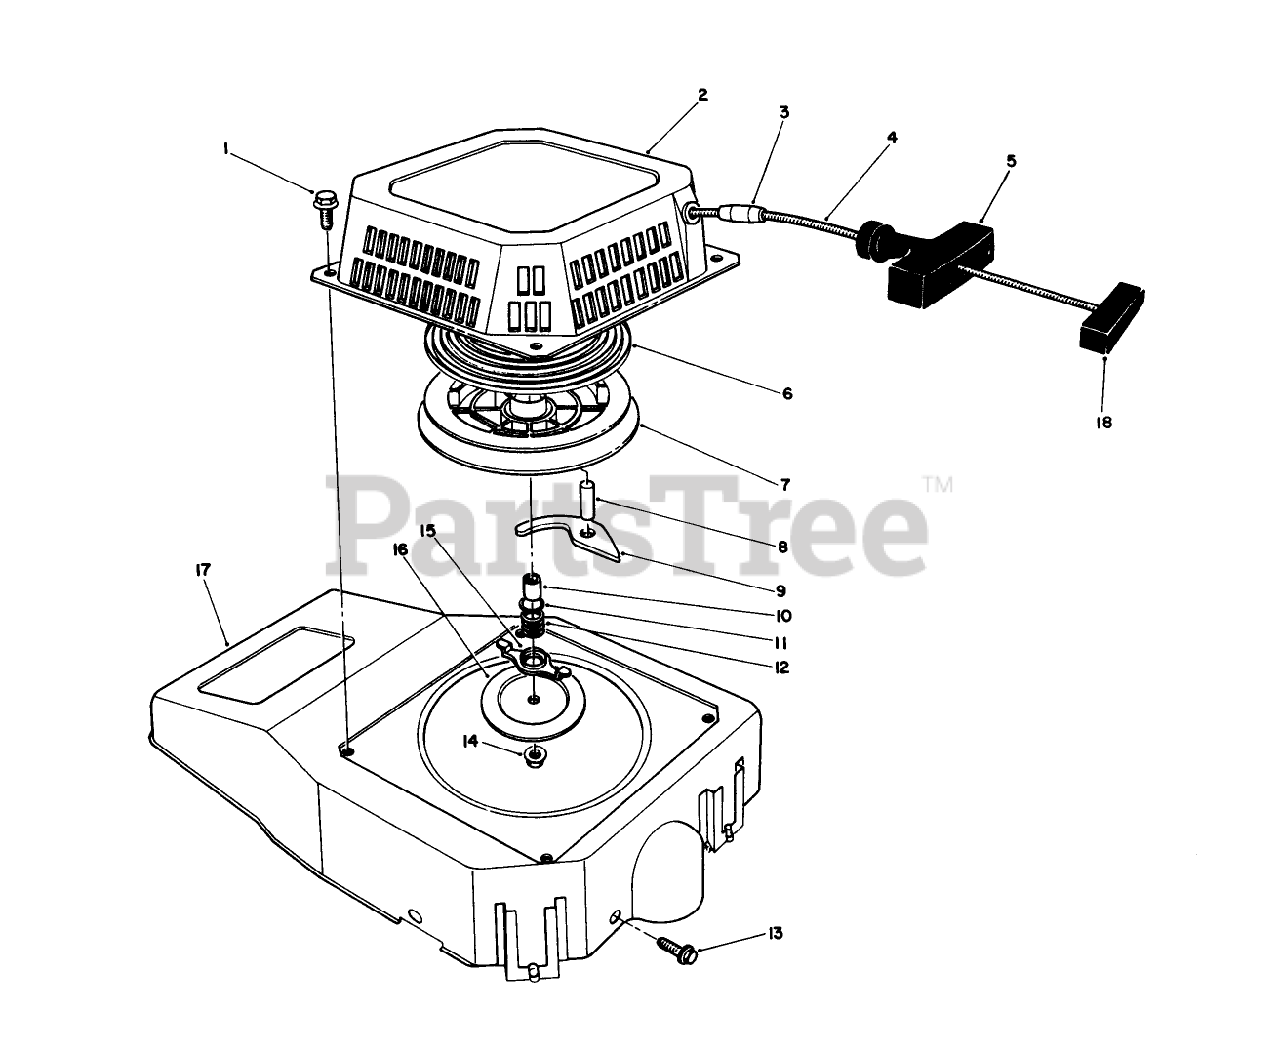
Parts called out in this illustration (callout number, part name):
1	SCREW-HHF
5	HANDLE
6	SPRING
11	WASHER
17	SHROUD
